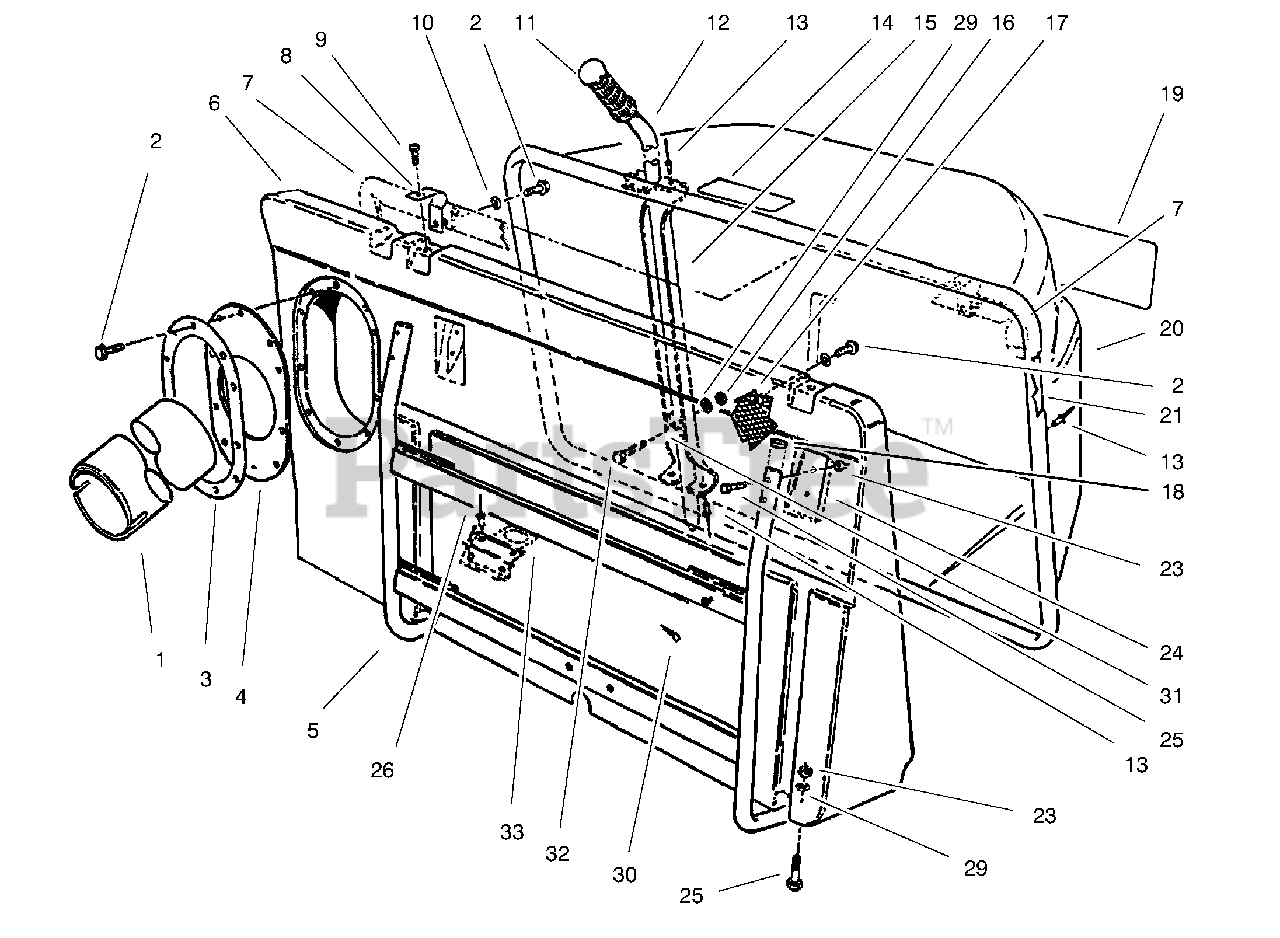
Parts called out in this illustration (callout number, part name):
2	Screw-Self Tapping
3	Ring-Retaining
5	Frame
6	Bag-Front
8	Bracket-Hinge
9	Screw-Button Head
10	Washer-Flat
11	Grip-Handle
12	Handle-Dump
13	Rivet-Pop
14	Decal-Warning
15	Channel-Dump Handle
16	Nut-Lock
17	Screen Bag
19	Decal-Easy-Empty
20	Basket-Grass
21	Frame-Grass Basket
23	Nut-Lock
24	Plate-Backup
26	Rivet-Pop
29	Washer-Flat
30	Pin-Cotter
31	Guide-Dump Handle
33	Latch
